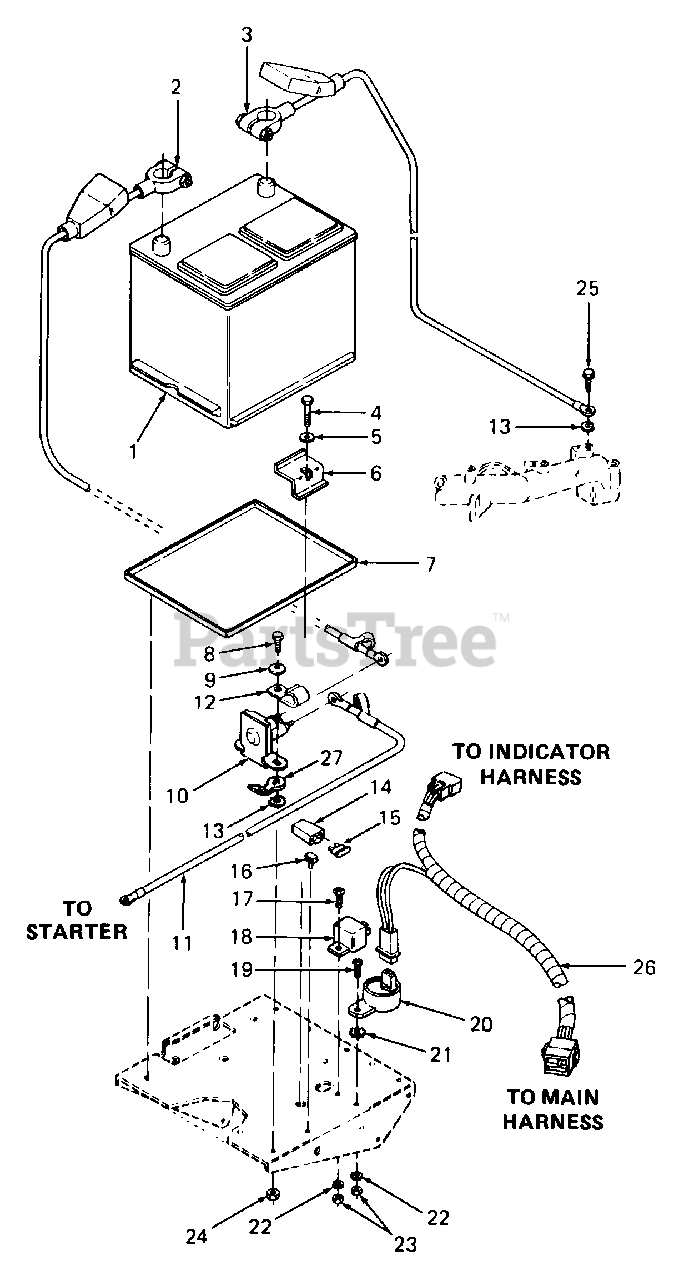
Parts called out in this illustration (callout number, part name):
1	Battery
2	Cable, Positive Battery
3	Cable, Negative Battery
4	Screw, Hex Cap, 5/16-18 x 1.38 Lg
5	Washer, Flat, .34 x .68 x .062 Thk
8	Screw, Hex Cap, 1/4-20 x .62 Lg GR5
9	Washer, Bell, .265 x .75 x .062 Thk
10	Solenoid
11	Cable, Starter
12	Clip, Cable
13	Washer, Int-Ext, 1/4
14	Holder, Fuse
15	Fuse, 20 Amp
16	Clip, Fuse Holder Mtg
17	Screw, Truss Mach, #10-24 x .50 Lg
18	Relay
19	Screw, Truss Mach, #10-24 x .50 Lg
20	Indicator, Voltage
21	Washer, External, #10
22	Washer, Lock, #10
23	Nut, Hex, #10-24
24	Nut, Hex Center Lock, 1/4-20
25	Screw, Hex Wash Hd Tapp, 1/4-20 x .38 Lg
26	Battery Harness
27	Lug, Quick Connect
